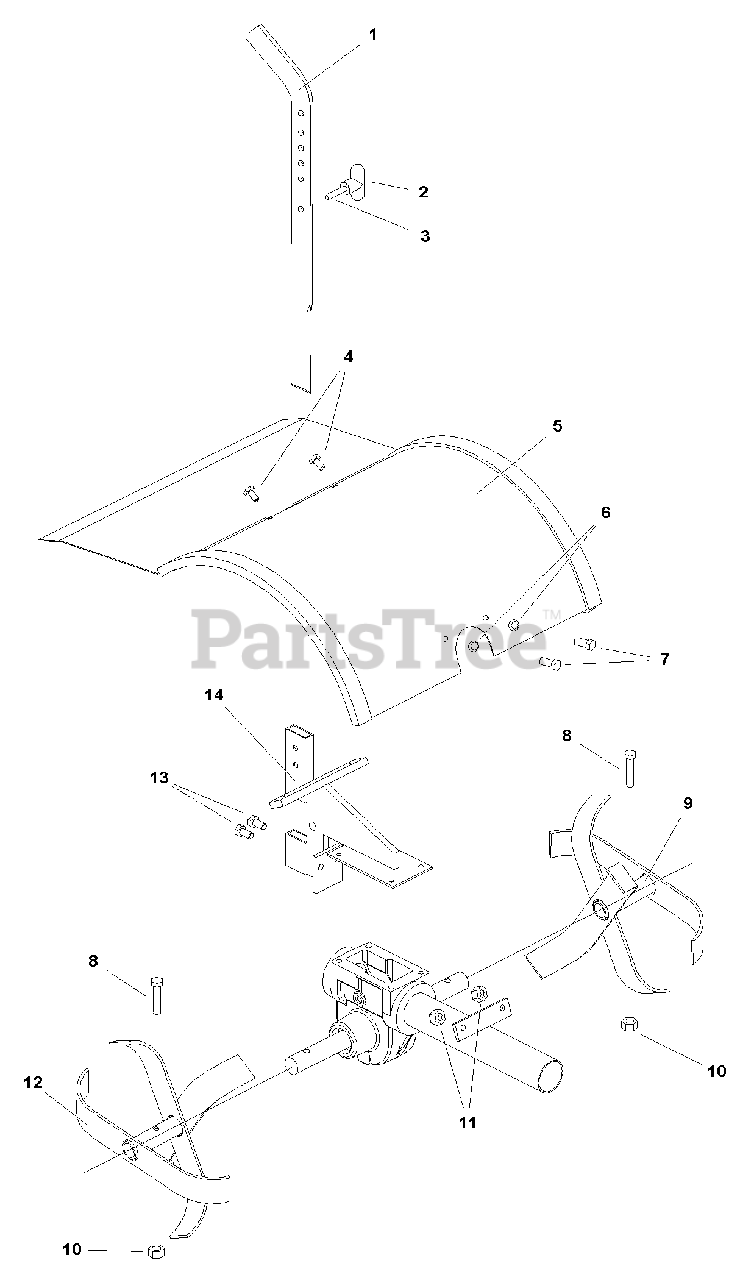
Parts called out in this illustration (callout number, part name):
1	LEVER, Depth Regulator
2	KNOB, T handle, Drag Stake
3	PIN, Detent 5/16"-18 x 1"
4	CAPSCREW, 1/4"-20 x 1/2" G5
6	LOCKWASHER, Spring 5/16"
7	CAPSCREW, 5/16"-18 x 1/2" G5
8	CAPSCREW, 3/8"-16 x 1 3/4" G5
9	TINE ASSEMBLY, LH
10	NUT, Hex, 3/8"-16NC, 2B
11	NUT, Hex Flange Head, 5/16"-18 Two, Way Lock
12	TINE ASSEMBLY, RH
13	CAPSCREW, Hex Flange Head, 5/16"-18 x 1/2"
14	BRACKET, Depth Regulator
